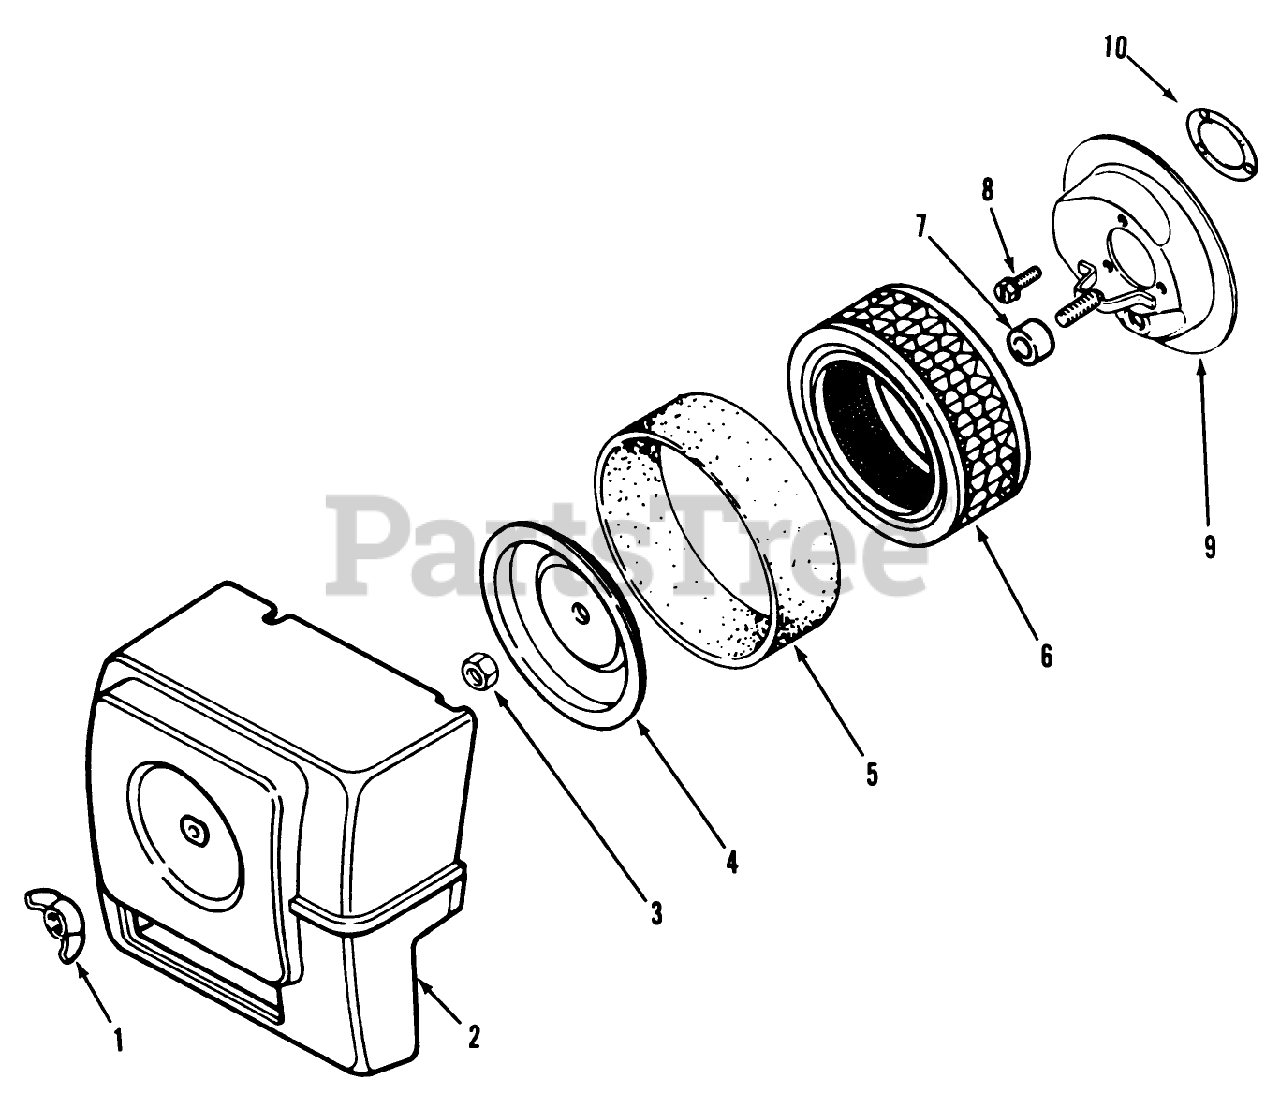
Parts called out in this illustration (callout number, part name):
1	KOHLER X-276-7
2	KOHLER 47-096-10
3	KOHLER 41-100-04
4	KOHLER 52-082-04
5	KOHLER45-083-01
6	KOHLER 45-083-02
7	KOHLER 231032
8	KOHLER X-67-65
9	KOHLER 47-094-20
10	KOHLER 45-041-07
